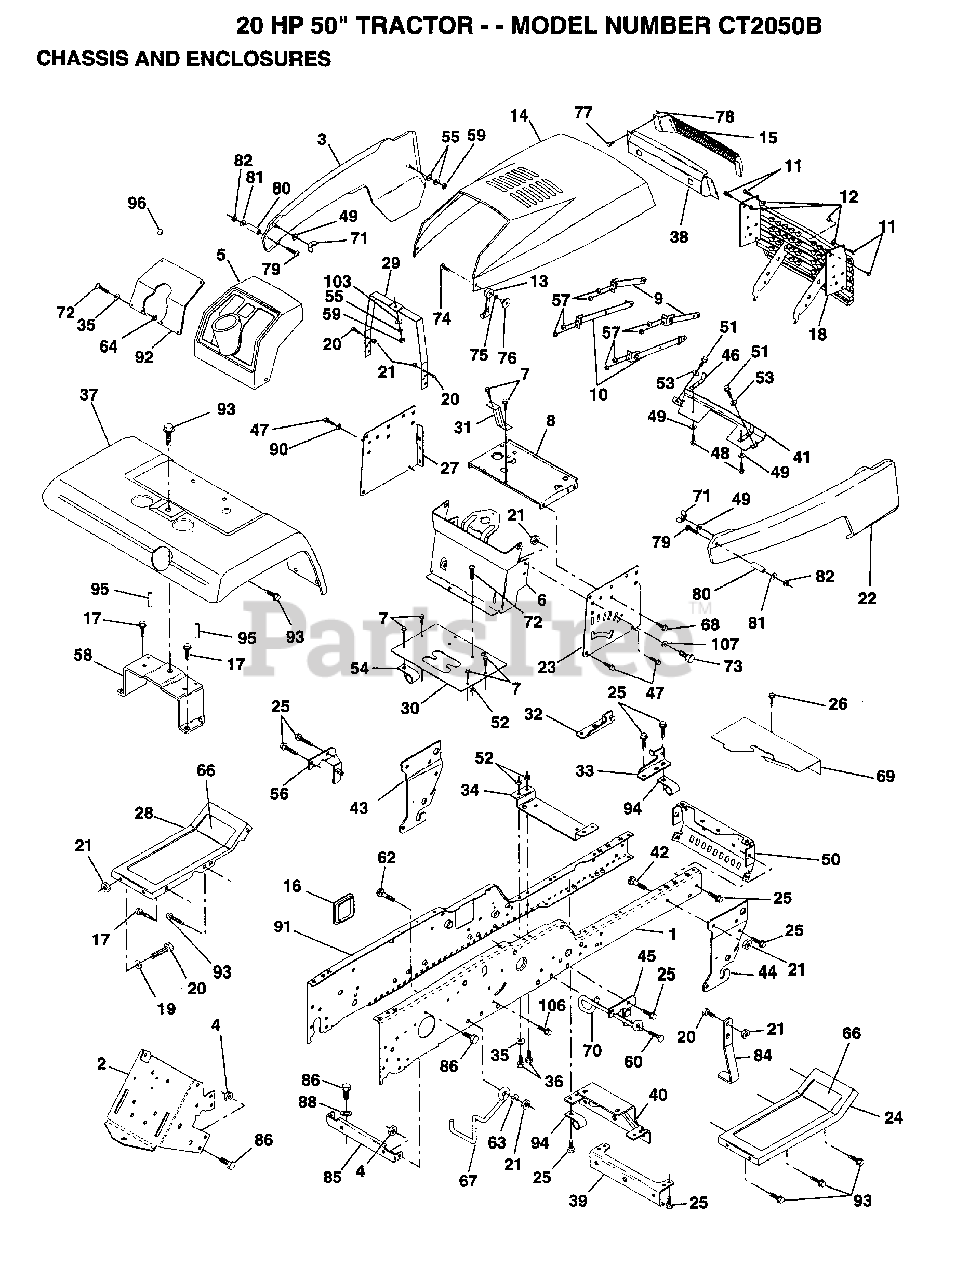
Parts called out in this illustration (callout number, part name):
2	DRAWBAR GT
3	PANEL SIDE LH ASM
4	NUT.7/16
5	DASHBOARD BLACK
6	DASH ASM LOWER
7	SCREW
8	SUPPORT BATRY VGT
12	NUT
13	HOOD LATCH T
15	LENS LT
16	COVER ACCESS
17	SCREW
18	GRILLE.ASM.PNT.YP
19	WASHER
20	BOLT
21	NUT
22	PANEL SIDE RH ASM
25	SCREW
26	SCREW
29	SUPPORT ASS'Y
30	SADDLE SILKSCRN
31	BRACE.SUPT.STRG
32	BRACKET ASM FRAME
33	BRACKET ASM FRAME
35	WASHER
36	BOLT
39	BRACKET.AXLE.FRT.
41	"STRAP,GRILL "
43	BRACKET.SUS.FT.LH
44	BRACKET.SUS.FT.RH
47	SCREW LT
48	SCREW
49	WASHER
50	BRACKET.CHASSIS.
51	SCREW HEX CRT
52	NUT
53	WASHER
54	"CLIP,INSULATOR"
55	WASHER PM
57	NUT
58	BRKT.ASM.FENDER
60	SCREW
62	BOLT D
63	WASHER
66	FOOTREST PAD
67	GUIDE BELT TRANS
68	SCREW LT
69	SHIELD.HEAT.MUF
70	GUIDE.BELT.MID.SP
73	BOLT
74	SCREW
75	LOCKWASHER
76	WELDNUT
78	"""J"" FASTENER LT"
79	SCREW
80	SPACER LT
81	WASHER
86	BOLT
88	LOCKWASHER
90	LOCKWASHER
92	PLATE SLKSCR YP
93	SCREW LT
94	CLIP GTV
95	NUT-PUSH YT
96	PLUG-DASH T
103	LOCKWASHER
106	BOLT.5/16-18X1.25
107	WASHER
